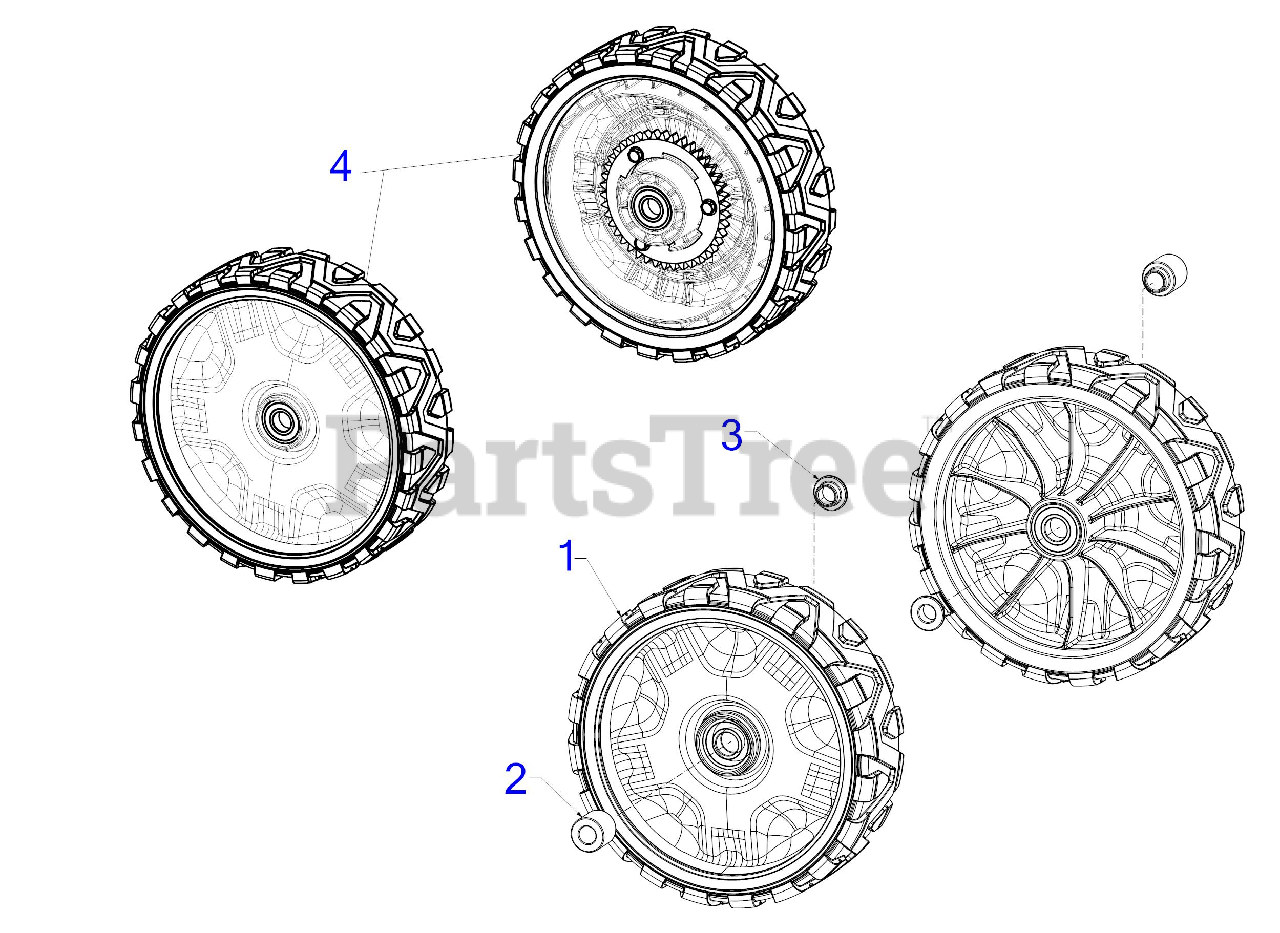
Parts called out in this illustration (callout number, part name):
1	WHEEL ASSEMBLY (7 x 2)
3	CASTER HUB
4	WHEEL ASSEMBLY (8 x 2)
